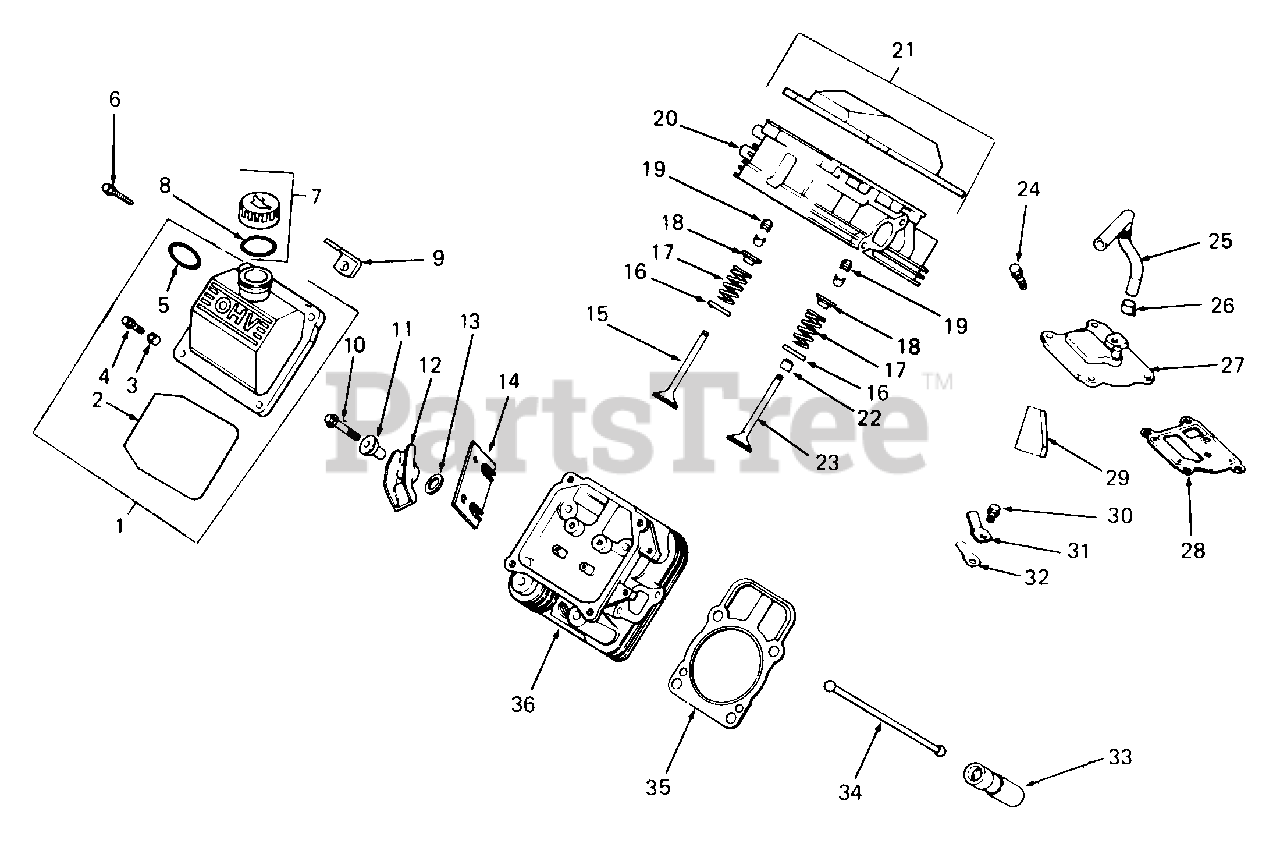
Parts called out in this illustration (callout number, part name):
1	Kit, Valve Cover w/Oil Fill
2	O-Ring, Cover
4	Screw, M6 X 1.0 X 30
5	O-Ring, Filler Neck
6	Screw, M10 X 1.5 X 91
7	Kit, Oil Fill Cap
8	O-Ring, Oil Fill Cap
9	Strap, Lifting
10	Screw, M6 X 1.0 X 34
11	Pivot, Rocker Arm
13	Washer, Flat
14	Plate, Guide
15	Valve, Exhaust, Std
16	Retainer, Spring
17	Spring, Valve
18	Cap, Valve Spring
19	Lock, Retainer
20	Head Assy, Cylinder #1
21	Kit, Valve Cover
22	Seal, Valve Stem
23	Valve, Intake, Std
24	Screw, M6 X 1.0 X 20
25	Hose, Breather
26	Clamp, Hose
27	Cover, Breather
28	Gasket, Breather
29	Filter, Breather
30	Screw, Breather Reed Retainer, M5 X 0.8 X 10
31	Retainer, Breather Reed
32	Reed, Breather
33	Lifter, Valve
34	Rod, Push
35	Gasket, Cylinder Head
36	Head Assy, Cylinder #2
